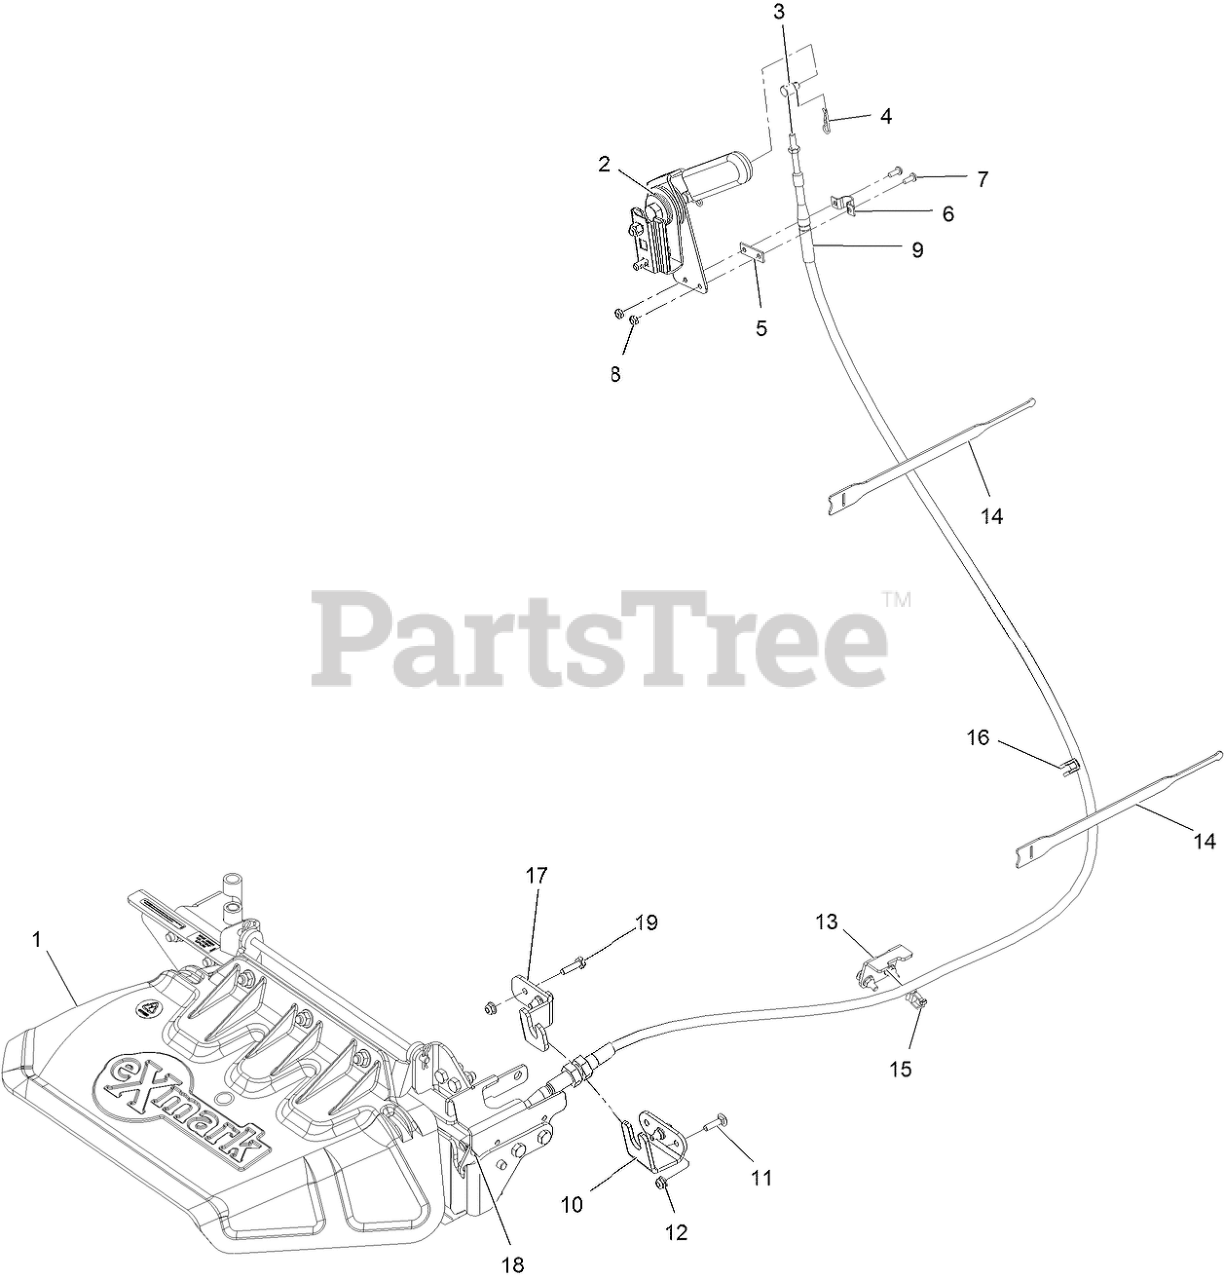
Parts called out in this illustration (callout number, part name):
1	ASM, OCD
2	ASM, HAND LEVER
3	PIVOT, CONTROL CABLE
4	PIN-COTTER
5	SHIM,CONTROL CABLE
7	SCREW-PPH
8	NUT-LOCK, NI
9	CABLE,DISCHARGE GATE
10	BRKT-OCD CABLE
11	SCREW-CARR
13	BRKT-CABLE
14	STRAP-VELCRO, CABLE TIE
15	CLIP-TIE
16	Clip-Edge
17	BRKT-OCD CABLE
18	NUT-LOCK
19	SCREW-HH
